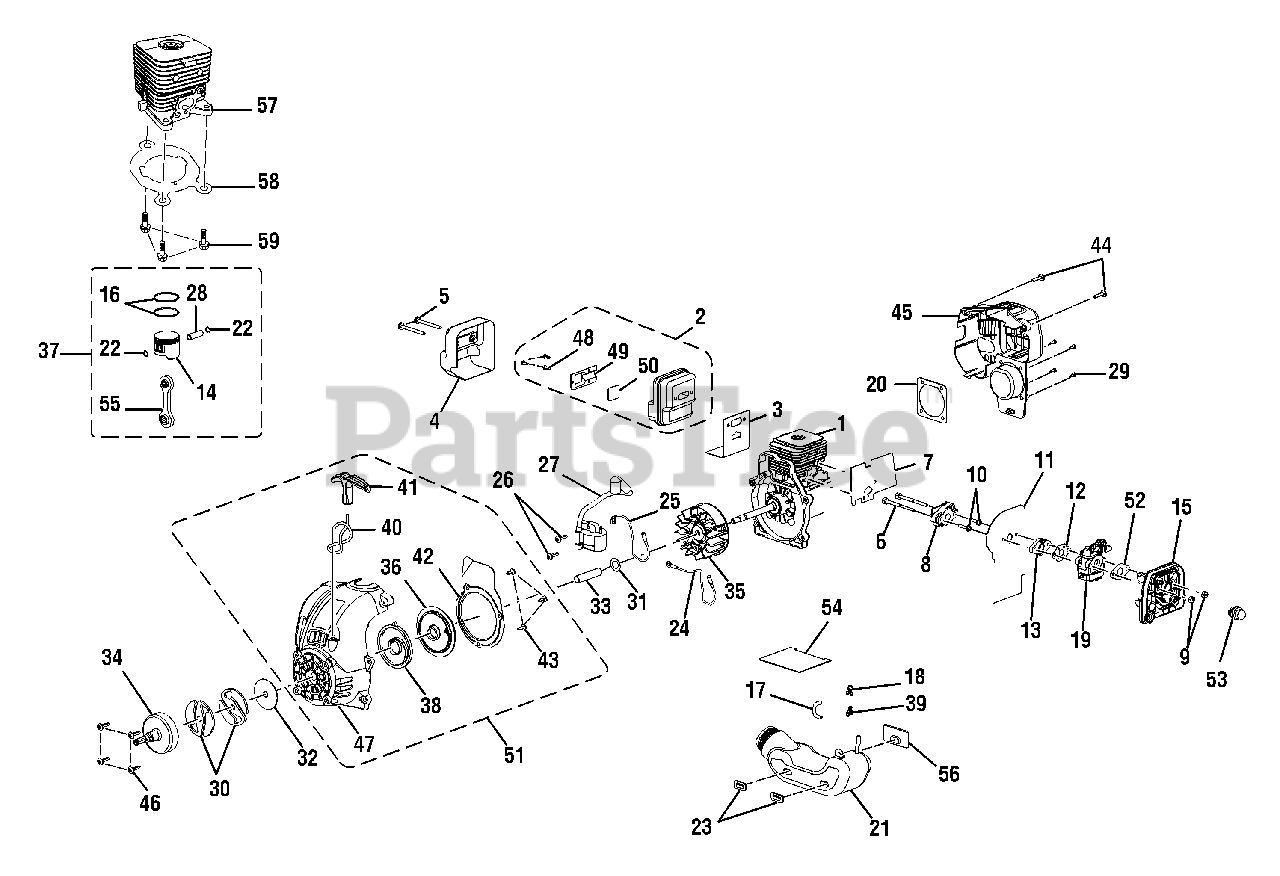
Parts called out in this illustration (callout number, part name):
1	SHORT BLOCK ASSEMBLY
2	MUFFLER ASSEMBLY
3	MUFFLER GASKET
4	HEAT SHIELD
5	SCREW (10-24 X 2-1/8 in. TORX TRUSS HD. SEMS)
6	BOLT (10-27 X 2-3/8 in. HEX HD.)
7	HEAT DAM GASKET
9	LOCK NUT (10-24)
10	SCREW (10-24 X 1 in. TORX PAN HD. SEMS)
11	CARBURETOR GASKET
12	CARBURETOR GASKET
14	PISTON W/PIN
15	AIR FILTER BOX
16	PISTON RING 30cc
17	RUBBER TUBING (2 in.)
19	CARBURETOR
20	GASKET, C/C COVER
21	FUEL TANK W/CAP ASSEMBLY
22	RETAINING RING
24	LEAD W/TERMINALS
26	SCREW (8-32 X 1 in. THREAD FORMING)
27	IGNITION MODULE (W/ 3 SEC. KILL)
28	PISTON PIN
29	SCREW (10-24 X 3/4 in. PAN HD. TORX)
32	WASHER
34	DRUM & CONNECTOR
35	ROTOR AND PAWL ASSEMBLY
36	STARTER PULLEY
37	PISTON ASSEMBLY
38	SPRING & CONTAINER
40	STARTER ROPE
41	STARTER GRIP
43	SCREW (8-16 X 1/2 in. THD. FORM. )
44	SCREW (10-14 X 7/8 in. THD. FORM. )
45	REAR HOUSING
46	SCREW (10-24 X 3/4 in. TRUSS HD.)
47	STARTER HOUSING W/EYELET
48	SCREW (6-20 X 1/4 in. TRI-LOBULAR)
49	OUTLET TUBE
51	COMPLETE STARTER ASSEMBLY
53	PRIMER ASSEMBLY
54	TANK INSULATION GASKET
55	CONNECTING ROD ASSEMBLY
56	RUBBER BUMPER
57	CYLINDER
58	CYLINDER GASKET
59	SCREW (12-24 X 5/8 in.)
